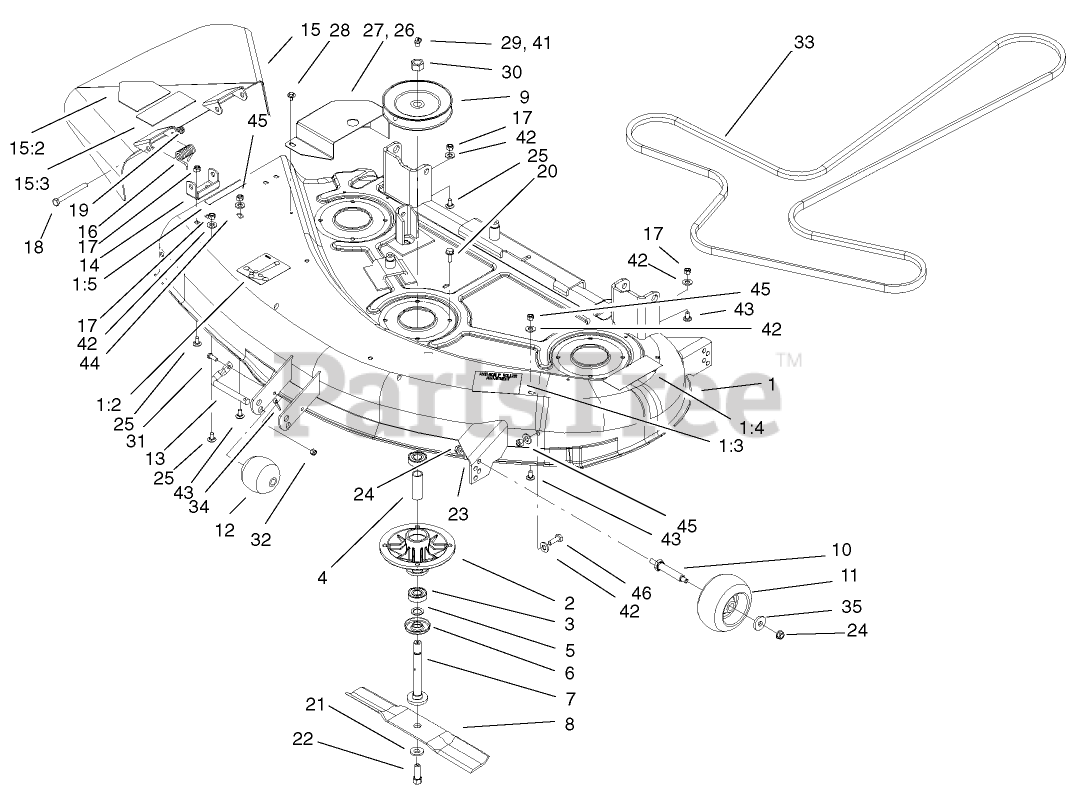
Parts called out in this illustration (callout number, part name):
1	44 INCH DECK ASM
1:2	DECAL-ROUTING, BELT
1:3	DECAL-WHEEL, GAGE
1:4	DECAL-DANGER
1:5	DECAL-CAUTION
2	HOUSING-SPINDLE
3	BEARING-BALL
4	SPACER-BEARING
5	SPACER
6	SHIELD-BEARING
7	SHAFT-CENTER, SPINDLE
9	PULLEY ASM
12	ROLLER
13	SHAFT-ROLLER
14	BRACKET-PIVOT
15	DEFLECTOR/DECAL ASM
15:2	DECAL-DANGER
15:3	DECAL-DANGER
16	SPRING
17	NUT-LOCK, NI
18	SCREW-HH
19	NUT-HEX
20	SCREW-TAPTITE
21	WASHER-BELLEVILLE
22	SCREW-HH
23	WASHER-BELLEVILLE
24	NUT-HHF, WHIZ
25	SCREW-CARR
26	COVER-BELT, LH
27	COVER-BELT, RH
28	SCREW-HHFTF
29	FITTING-GREASE
30	NUT-HEX
31	SCREW-HH
32	NUT-LOCK, NI
34	PIN-COTTER
35	WASHER
41	FITTING-GREASE
42	WASHER-FLAT
43	SCREW-CARR
44	WASHER-FLAT
45	NUT-LOCK, NI
46	SCREW-HH
